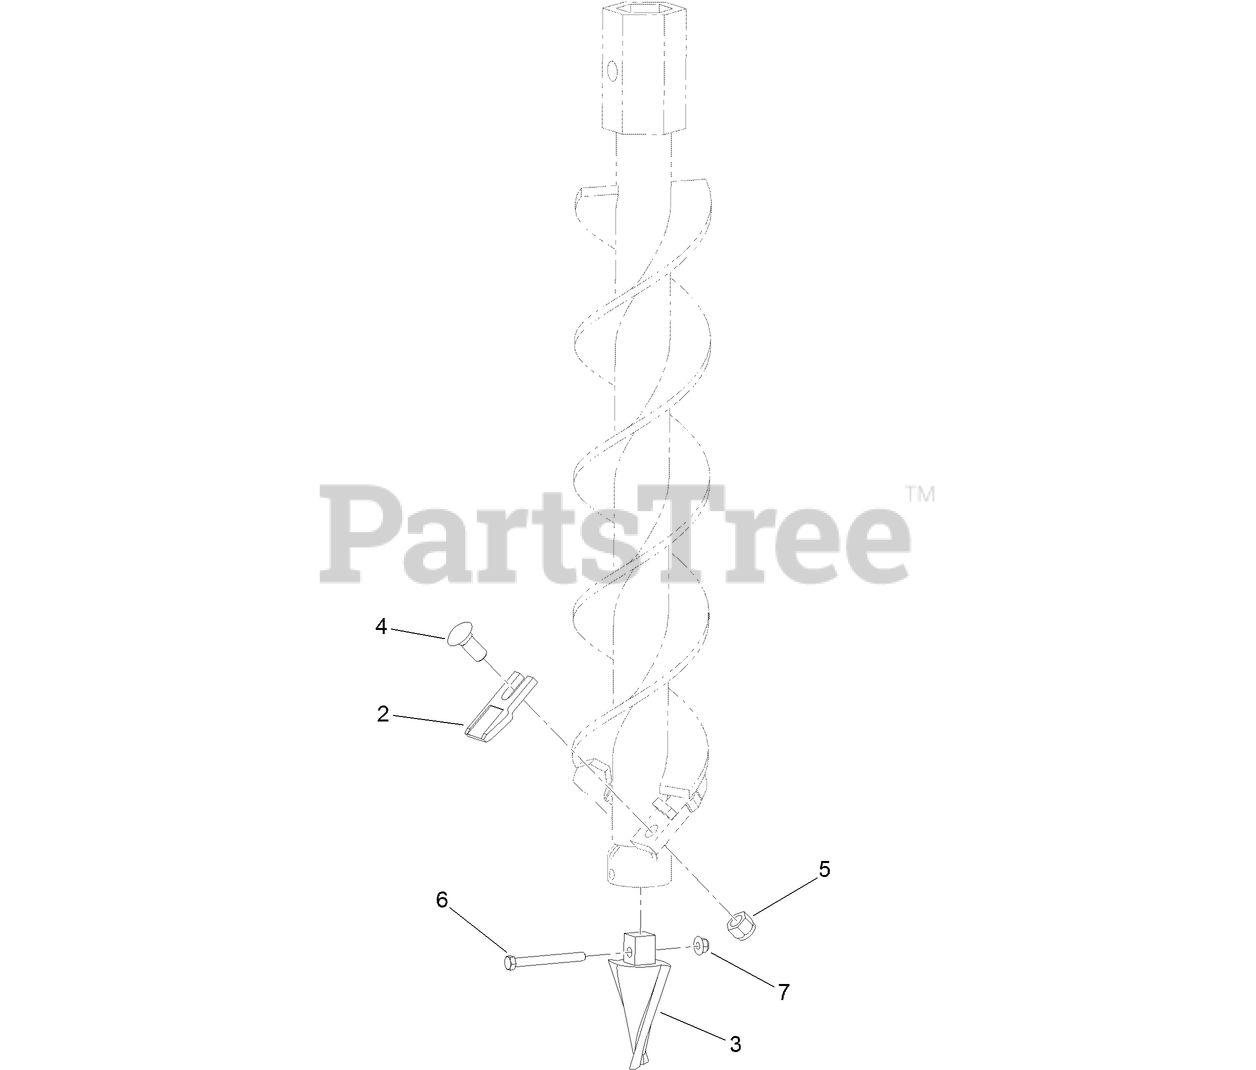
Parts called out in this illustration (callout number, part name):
2	TOOTH-AUGER, WISDOM (OUTER)
3	TOOTH-FISHTAIL, STANDARD
4	SCREW-CARRIAGE
5	NUT-LOCK, NI
6	SCREW-HH
7	NUT-HF, NI
